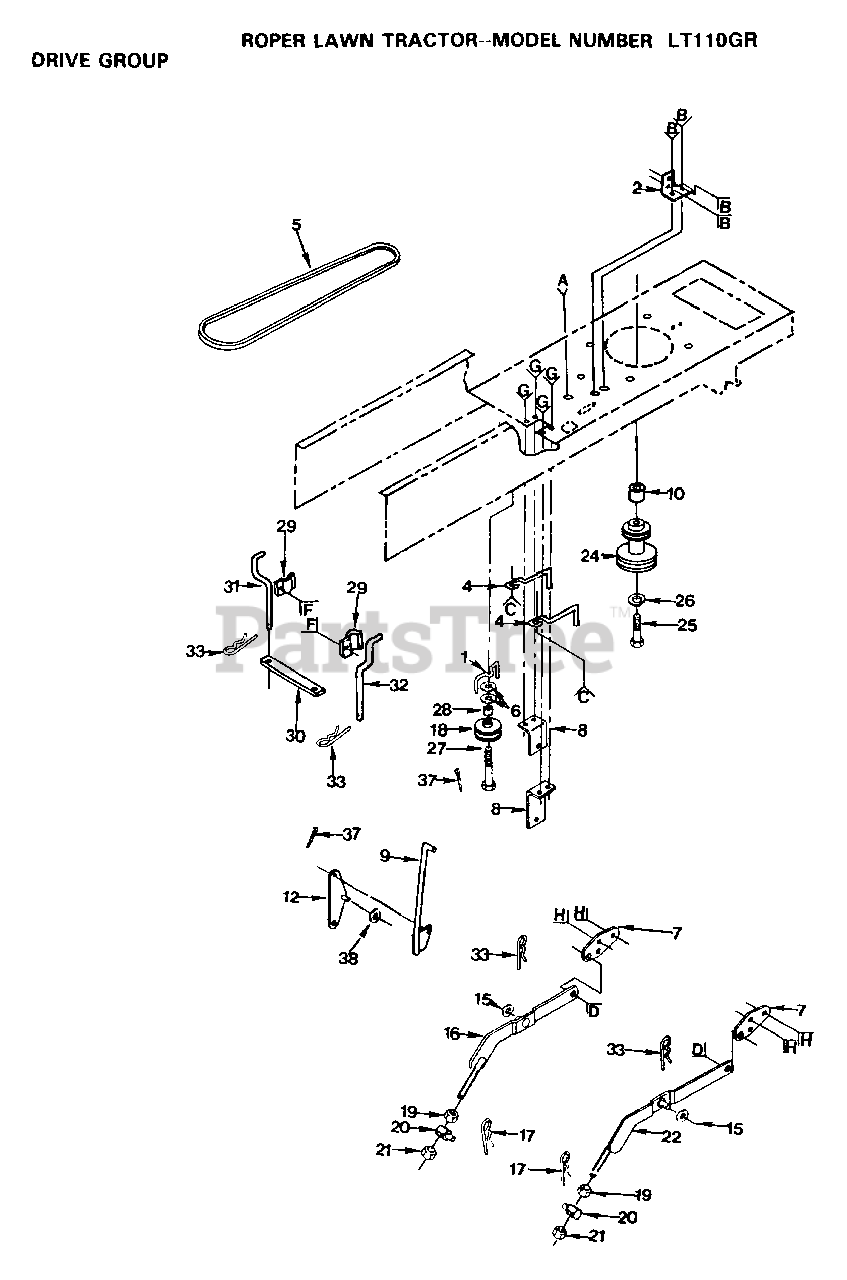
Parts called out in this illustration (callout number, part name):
1	BELT KEEPER LT
2	BRACKET LT
4	"KEEPER,BLT ENG LT"
6	WASHER
7	"BRACKET, SUSPE T"
8	"BRKT,BELLCRAN T"
9	ROD ASSEM YT
10	WASHER
12	"T, BELLCRANK"
17	SPRING H
19	NUT
21	NUT LTV
26	LOCKWASHER
27	BOLT
28	SPACER T
29	CLAMP LT
33	SPRING.RETAINER
37	COTTER PIN
38	WASHER
